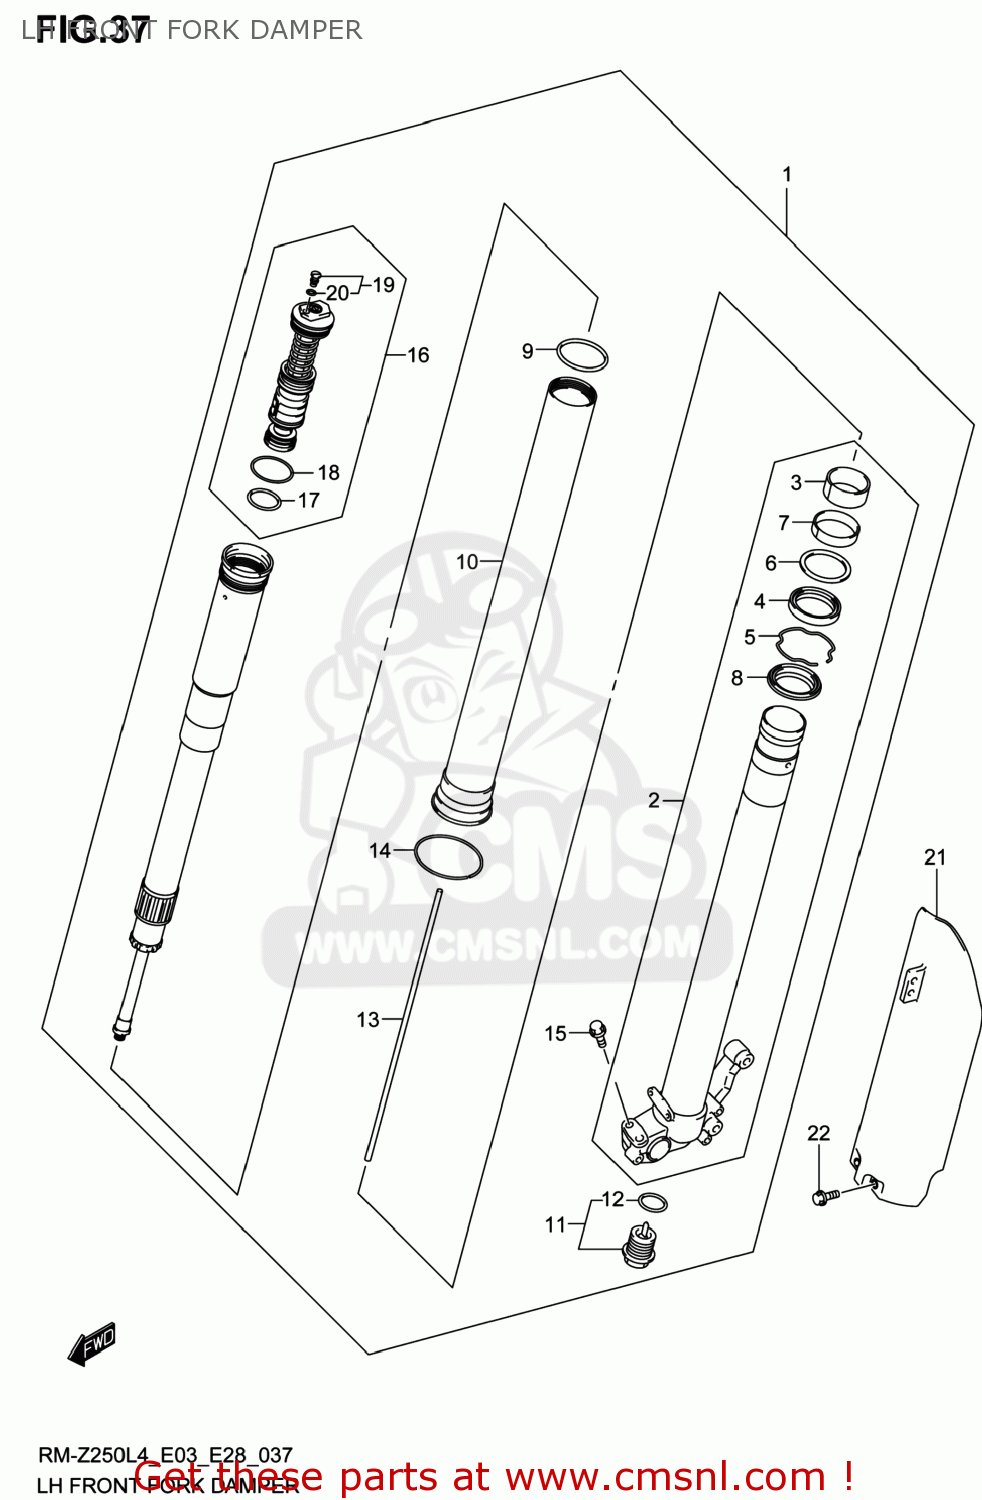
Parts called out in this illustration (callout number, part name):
1	DAMPER ASSY,FR FORK,L
2	TUBE,INNER,L
3	BUSH,SLIDE
4	SEAL,OIL
5	RING,OIL SEAL STOPPER
6	SPACER,SEAL
7	BUSH,GUIDE
8	SEAL,DUST
9	O RING
10	TUBE,OUTER
11	BOLT,CTR
12	O RING
13	ROD,PUSH
14	STOPPER,RING
15	BOLT
16	BOLT,FORK
17	O RING
18	O RING,FORK BOLT
19	BOLT,PLUG
20	O RING,PLUG
21	PROTECTOR,FR FORK,L
22	BOLT(6X10)
